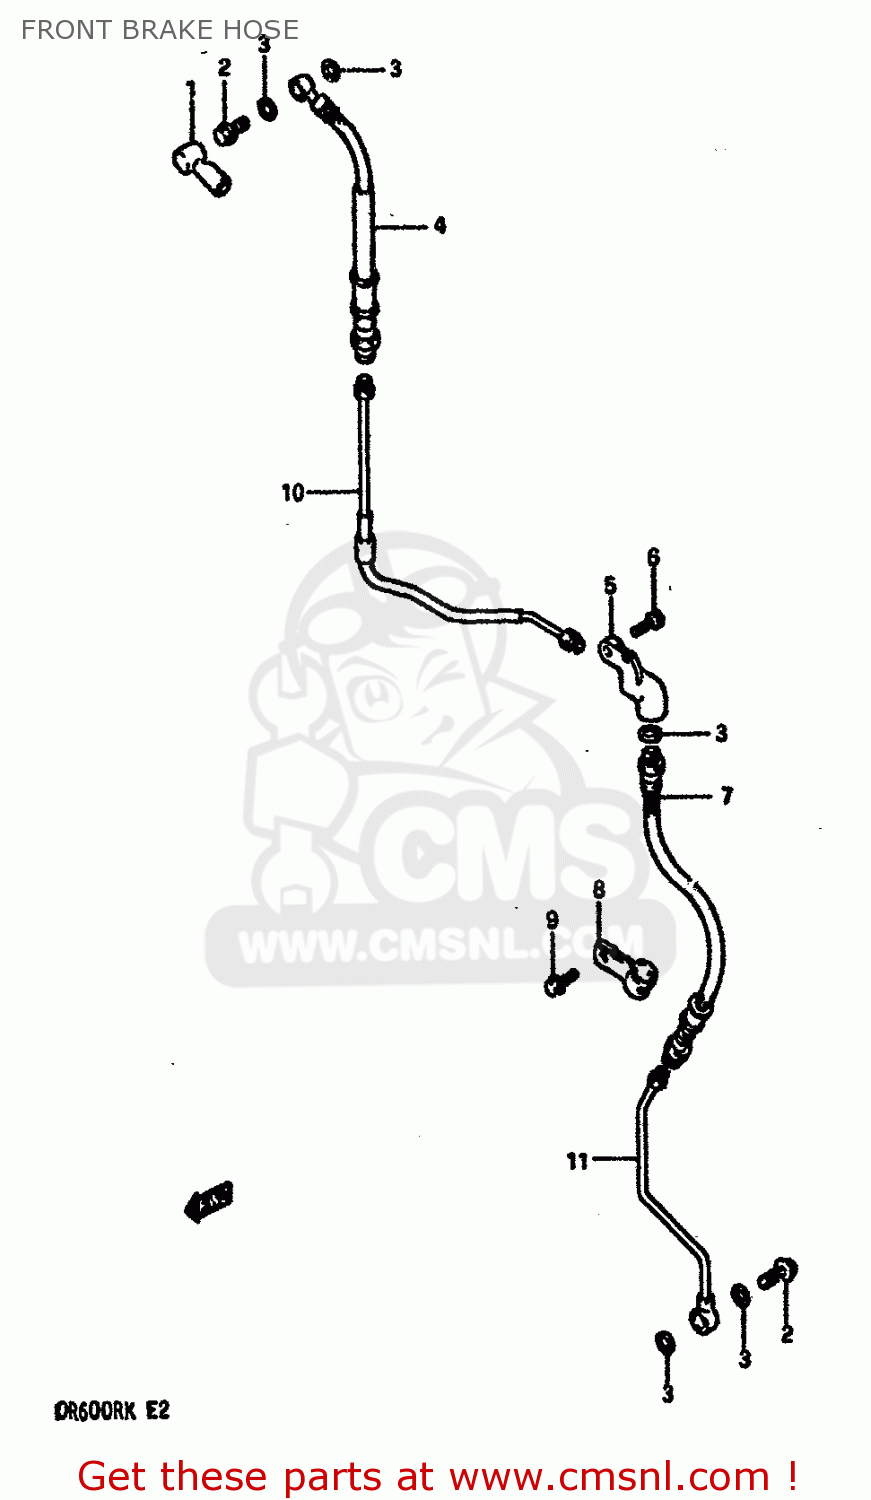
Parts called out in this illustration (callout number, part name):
1	BOOT,MASTER CYLINDER
2	BOLT,UNION
3	WASHER(10X15X1.5)
4	HOSE,FRONT BRAKE NO.1
5	JOINT,FRONT BRAKE
6	BOLT
7	HOSE,FR BRAKE NO.2
8	CLAMP,FRONT BRAKE HOSE
9	BOLT
10	PIPE,FRONT BRAKE NO.1
11	PIPE,FRONT BRAKE NO.2
